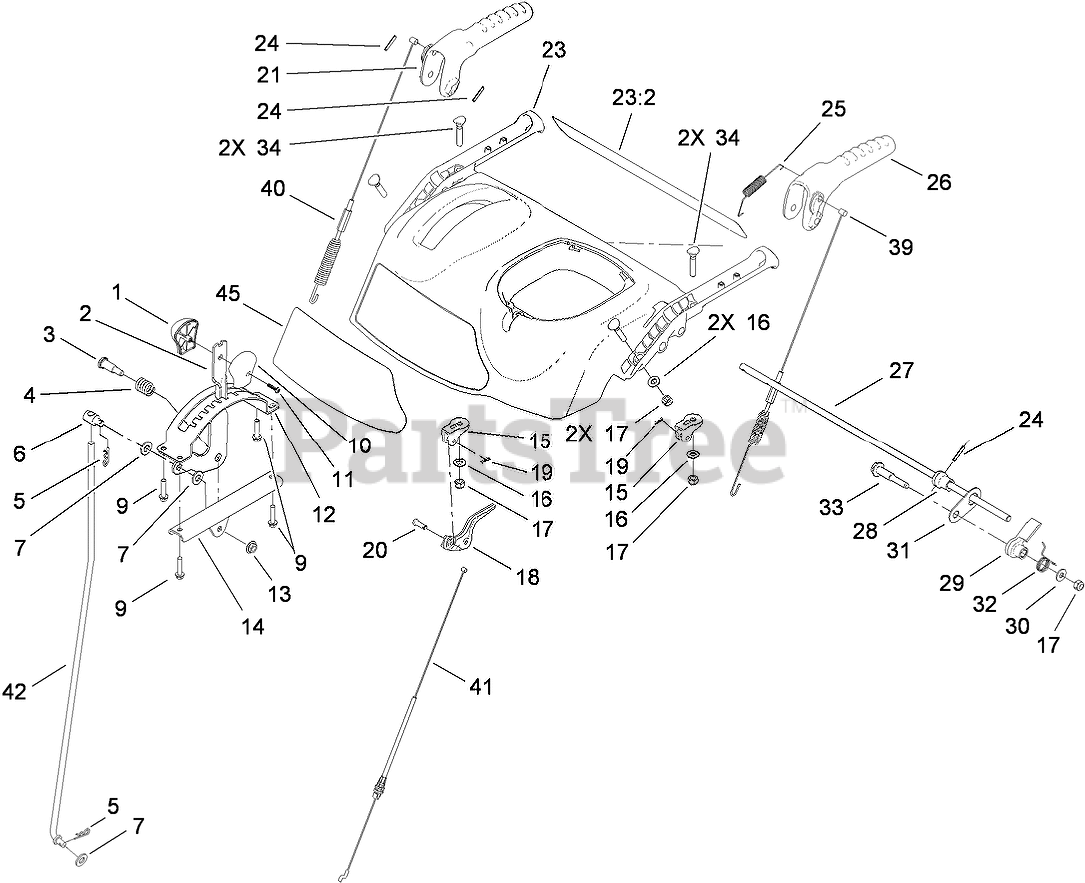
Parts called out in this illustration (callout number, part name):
1	KNOB-SHIFT, RH
2	SELECTOR-SPEED
3	SCREW-SHOULDER
4	SPRING-COMPRESSION
5	PIN-COTTER
6	TRUNNION-ROD
7	WASHER-FLAT
9	SCREW-PLASTITE
10	KNOB-SHIFT, LH
11	SCREW-PPH
12	GUIDE-SELECTOR, SPEED
13	NUT-HF
14	MOUNT-SELECTOR, SPEED
15	MOUNT-CLUTCH, LEVER
16	WASHER-FLAT
17	NUT-LOCK, NI
18	LEVER-CLUTCH
19	PIN-HAIR
20	PIN-CLEVIS
21	LEVER-AUGER
23	PANEL-CONTROL
23:2	DECAL-WARNING
24	PIN-SPRING
25	SPRING-TENSION
26	LEVER-TRACTION
27	ROD-LOCKOUT
28	CAM-LOCKOUT
29	LATCH-LOCKOUT
30	WASHER-FLAT
31	LINK-LOCKOUT
32	SPRING-TORSION
33	SCREW-SHOULDER
34	SCREW-HANDLE
39	CABLE-TRACTION
40	CABLE-AUGER
41	CABLE-CLUTCH
42	ROD-SHIFT
45	DECAL-CONTROL PANEL
